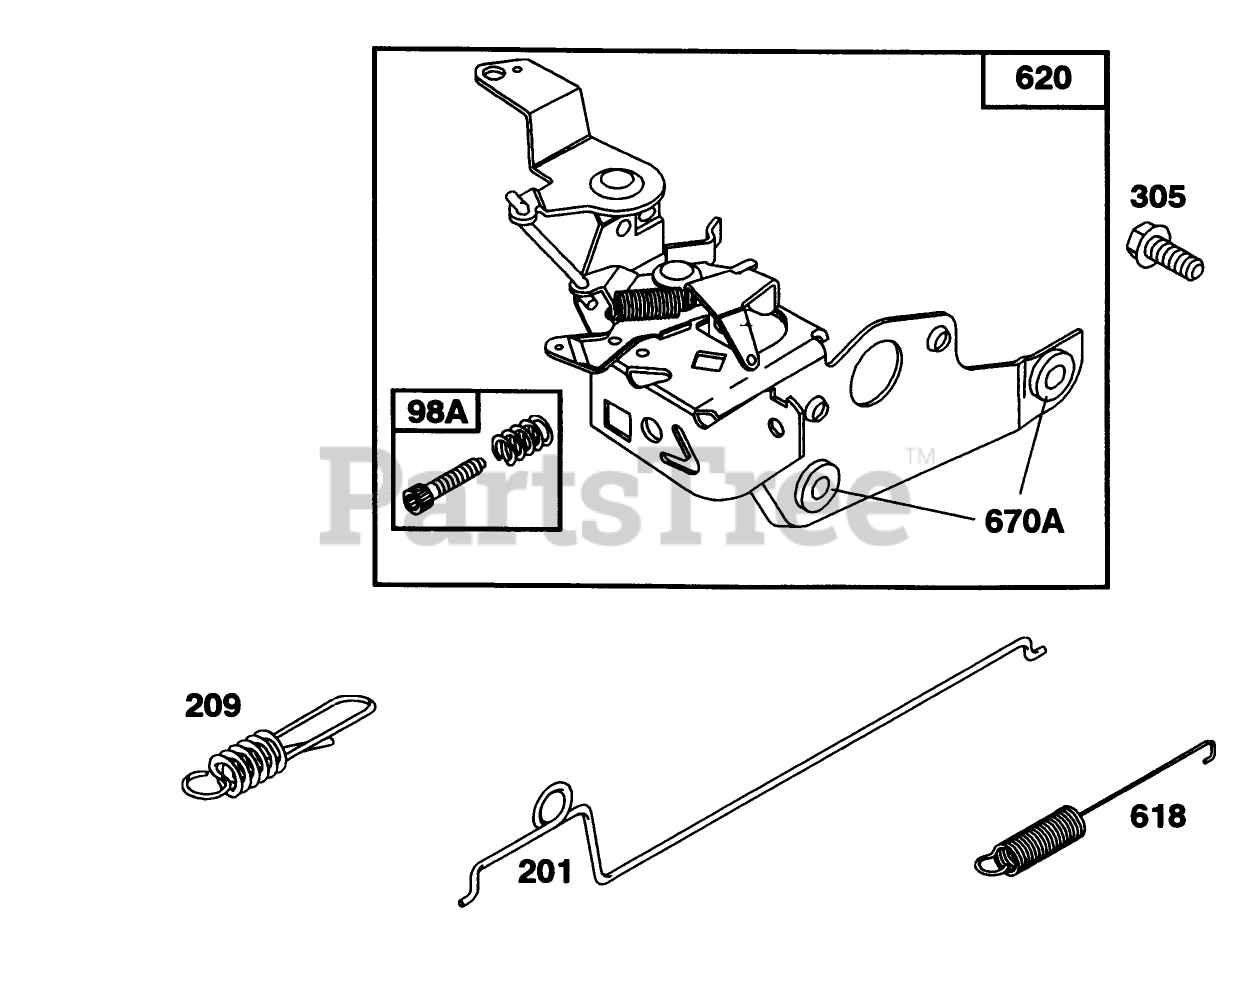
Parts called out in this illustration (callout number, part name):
98A	Screw Assy.
201	Link-Govemor
209	Spring-Govemor
305	Screw-Sem
618	Spring-Choke
620	Bracket Assembly
670A	Spacer
